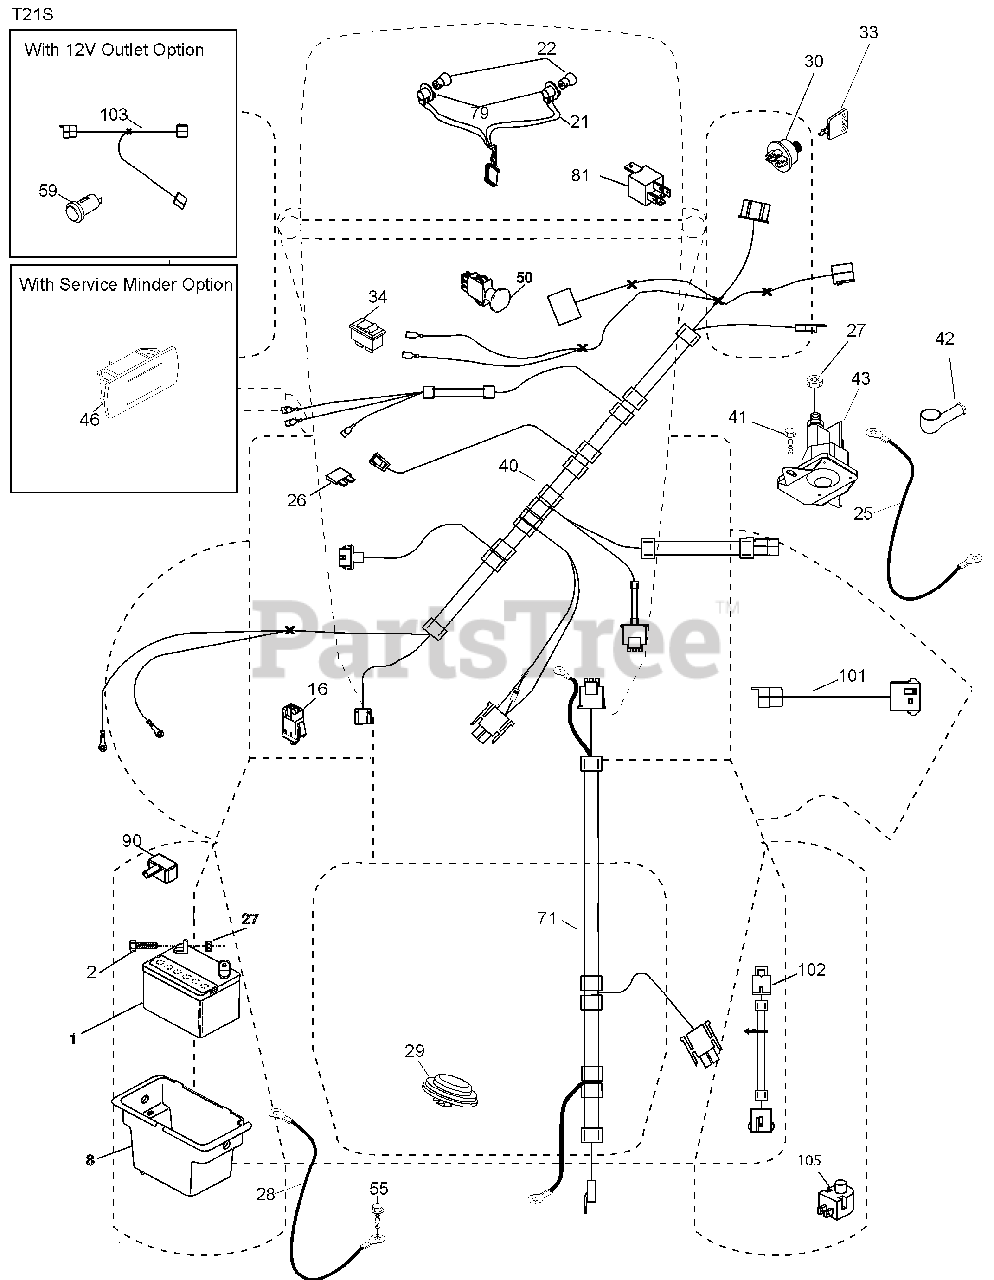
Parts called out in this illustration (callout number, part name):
1	Battery
2	Bolt Hex Head 1/4-20 x 3/4
8	Box Battery
16	Switch Interlock Push-In
21	Harness Socket Light W/4152J
22	Bulb Light
25	Cable Starter
27	Nut Keps Hex 1/4-20 unc
28	Cable, Ground
29	Switch, Seat
30	Switch, Ign
34	Switch Light / Reset
40	Harness Ign. Dash
41	Screw Thd Cut 1/4-20 x 1/2
42	Cover, Terminal
43	Solenoid
46	Gauge Servicereminder Hrmtr
50	Switch PTO
55	Screw Thdrol 5/16-18 x 3/4 TYTT
59	Outlet 12-Volt
71	Harness Ign.
79	Socket Asm Bulb Twistlock
81	Relay Harness Sealed
90	Cover Terminal
101	Harness Pigtail
102	Harness Pigtail
103	Harness 12-Volt Pigtail
105	Switch Reverse TT Pedal Control
